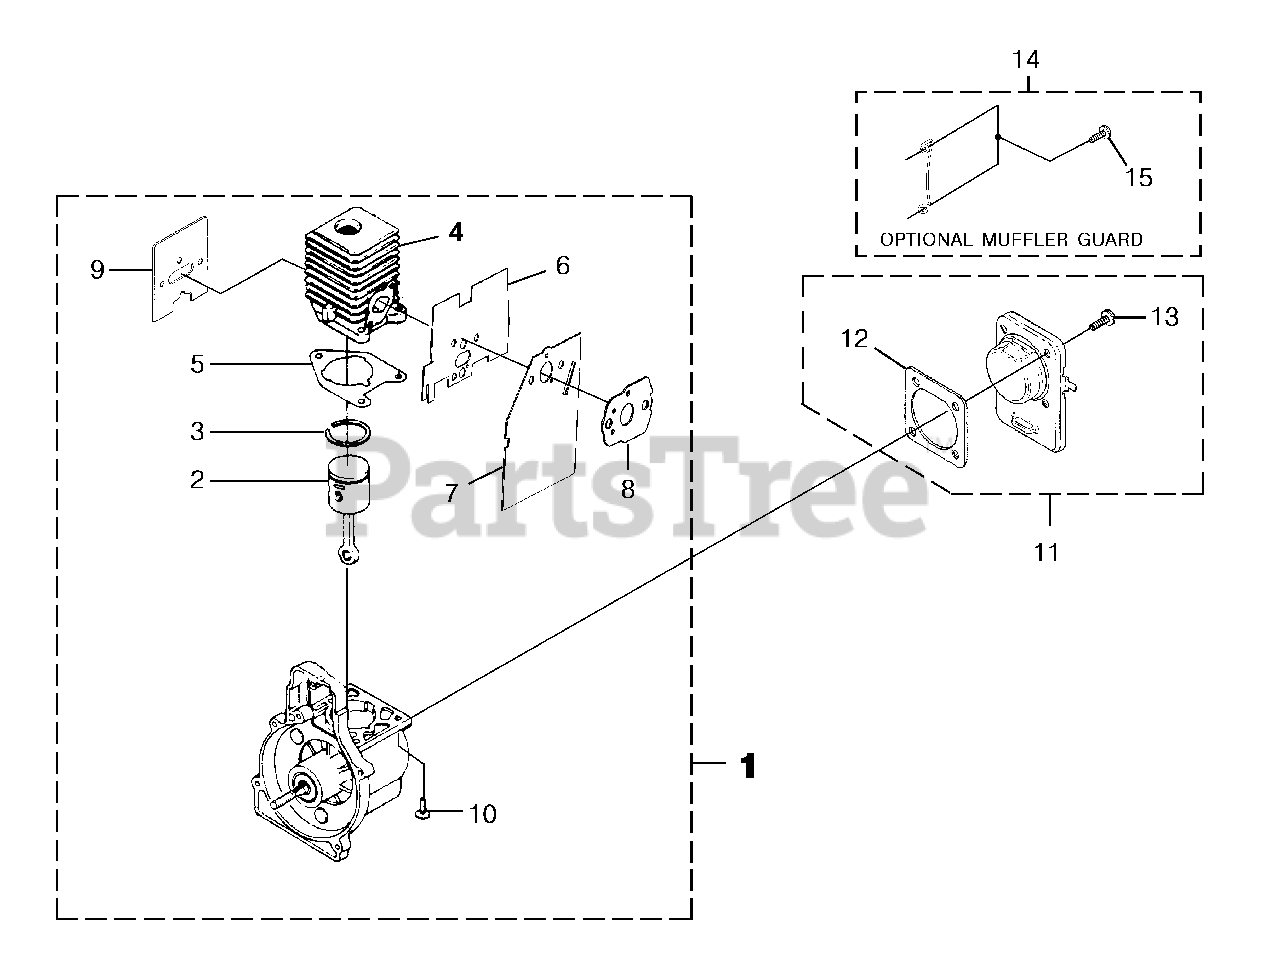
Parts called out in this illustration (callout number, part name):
1	SHORT BLOCK (Non-Clutch)
2	PISTON & ROD ASSY.
3	RING-Piston
4	CYLINDER ASSY.
5	GASKET-Cylinder
6	GASKET-Heat Dam to Cylinder
7	GASKET-Adaptor to Heat Dam
8	GASKET-Adaptor to Carburetor
9	GASKET-Muffler
10	SCREW-Sems (12-24 X 3/4")
11	CRANKCASE COVER ASSEMBLY
12	GASKET-Crankcase Cover
13	SCREW-Sems (10-24 X 1/2")
14	MUFFLER GUARD
15	SCREW-Plastite (10-14 X 1/2")
